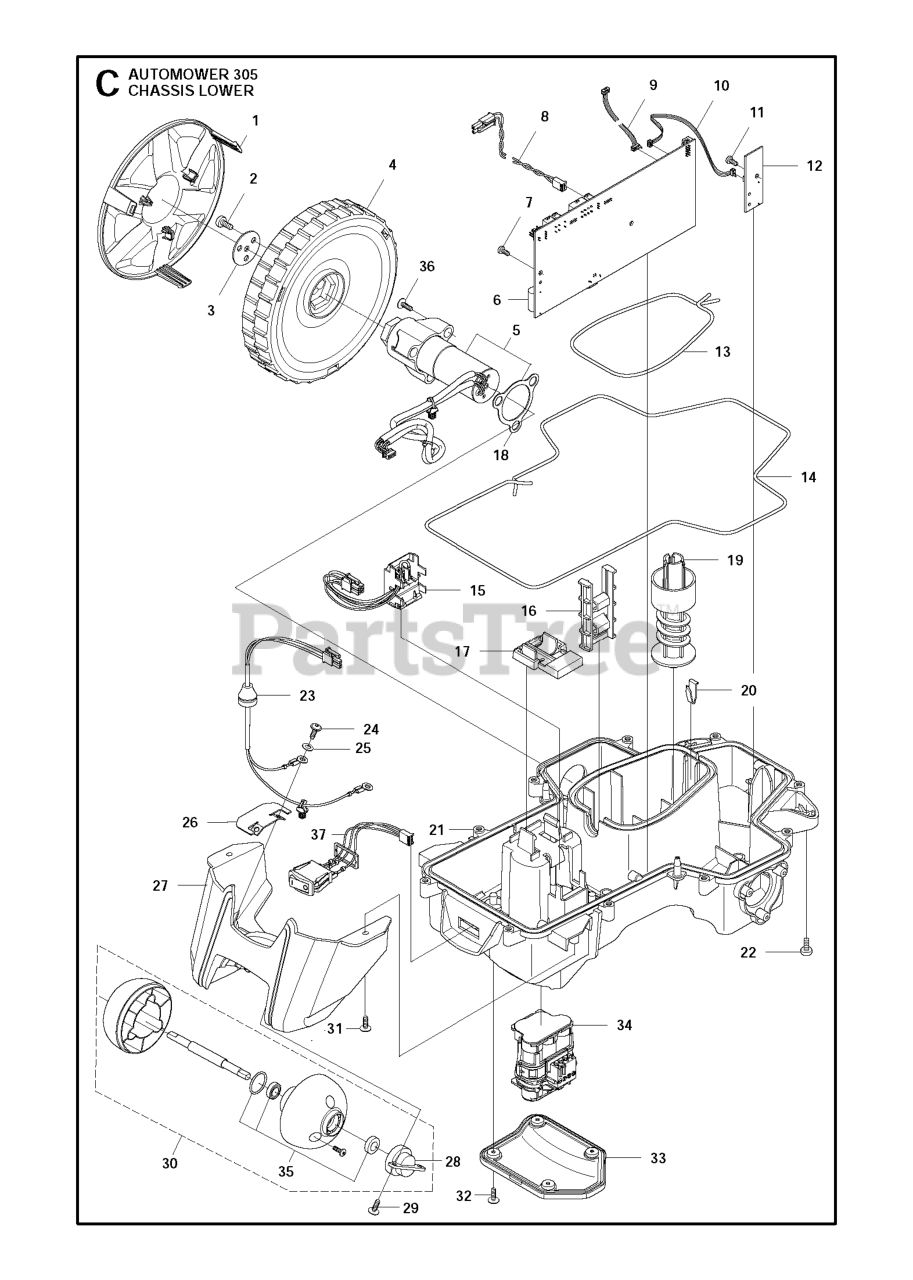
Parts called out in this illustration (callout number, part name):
2	SCREW ITXPANM M5X12 8.8 ZP-BC
3	WASHER DRIVE WHEEL
8	LOOM BUZZER EXTENSION
15	LOOM BATTERY 18 V LLITHIUM
16	GUIDE RAIL MOTOR BOWL
17	LOCK BATTERY PLUG
18	GASKET MOTOR FLANGE
19	SCREW HEIGHT ADJUSTMENT
20	LOCKING SPRING
22	SCREW ITXPANM M5X12 8.8 ZP-BC
24	SCREW 14MM
25	FIBER WASHER
28	BEARING HOUSING REAR WHEEL
29	SCREW 14MM
31	SCREW 14MM
32	SCREW ITXPANT
33	COVER BATTERY
34	BATTERY LI-ION
35	REAR WHEEL BEARING AND SEALING
36	SCREW 14MM
